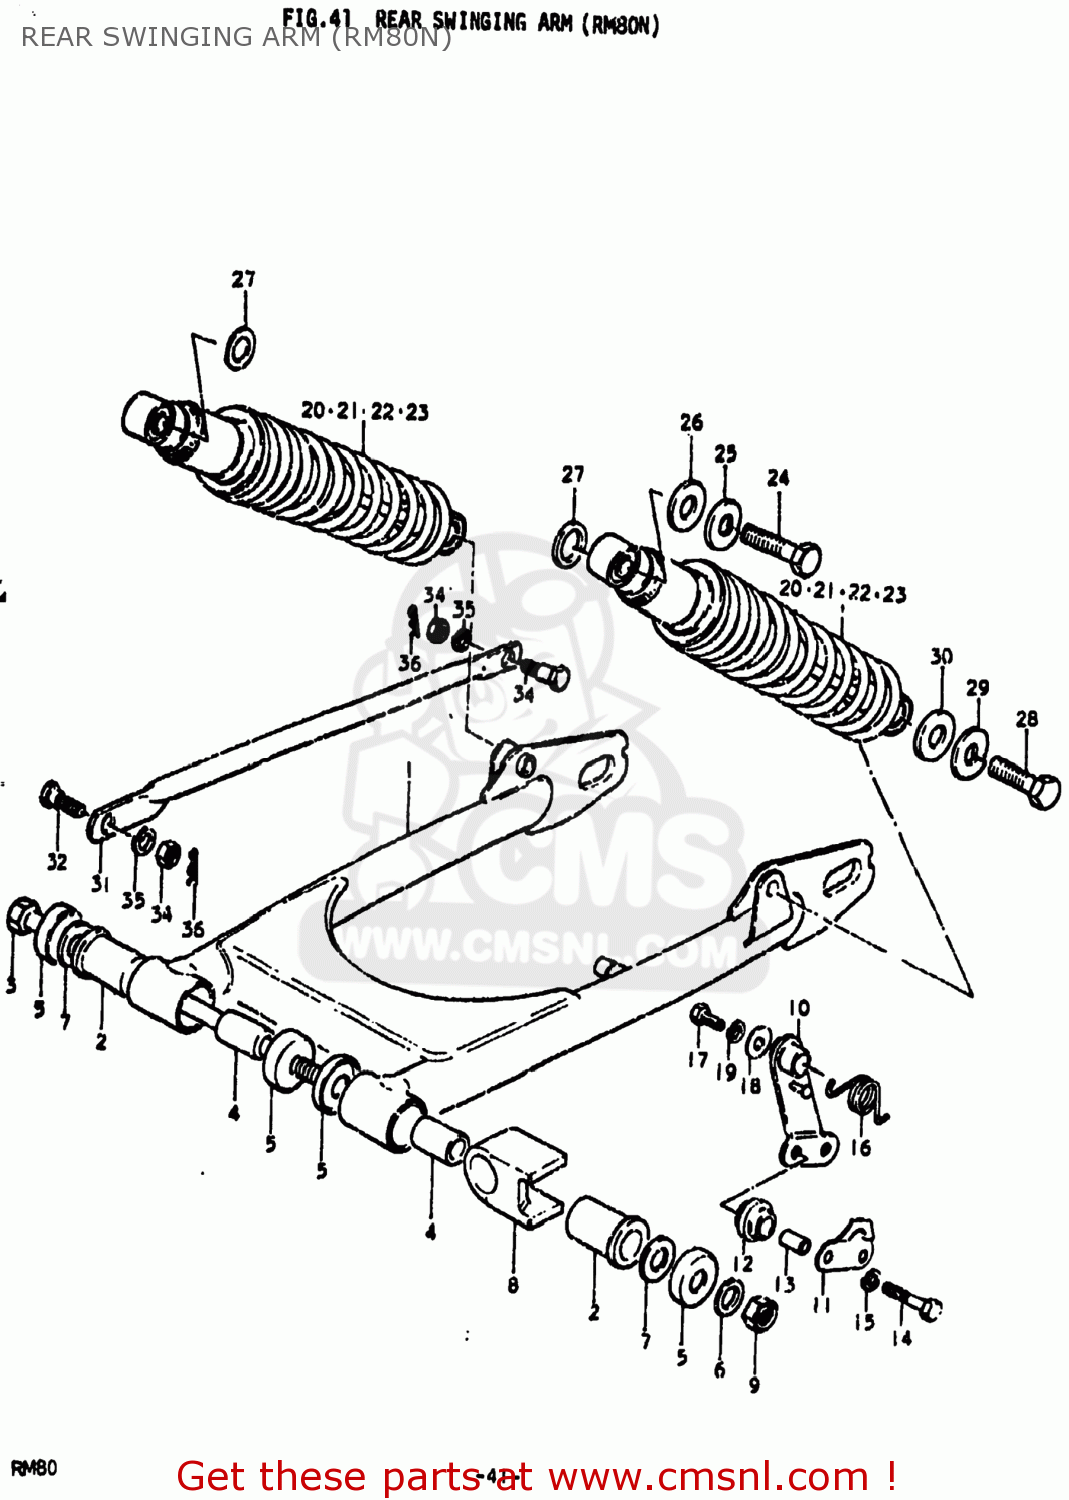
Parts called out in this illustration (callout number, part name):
1	SWING ARM ASSEMBLY,REAR
2	BUSHING
3	SHAFT, PIVOT
4	SPACER,RR SWGARM PIVOT
5	COVER,REAR SWING ARM DUST
6	WASHER
7	WASHER (10.2X28X1.5)
8	BUFFER,CHAIN TOUCH DEFLECTOR
9	NUT
10	TENSIONER,CHAIN
11	PLATE,CHAIN TENSIONER
12	RUBBER,CHAIN GUARD
13	SPACER(6.5X10.5X22.5)
14	BOLT
15	LOCK WASHER
16	SPRING
17	BOLT
18	WASHER
19	LOCK WASHER
20	ABSORBER ASSEMBLY,REAR SHOCK
21	SPRING
22	SPRING
24	BOLT
25	LOCK WASHER
26	WASHER (6.5X24X1.6)
27	WASHER
28	BOLT 10X40
29	LOCK WASHER
30	WASHER
31	TORQUE LINK,REAR
32	BOLT(8X22)
33	BOLT(8X26.5)
34	NUT
35	LOCK WASHER
36	CLIP
